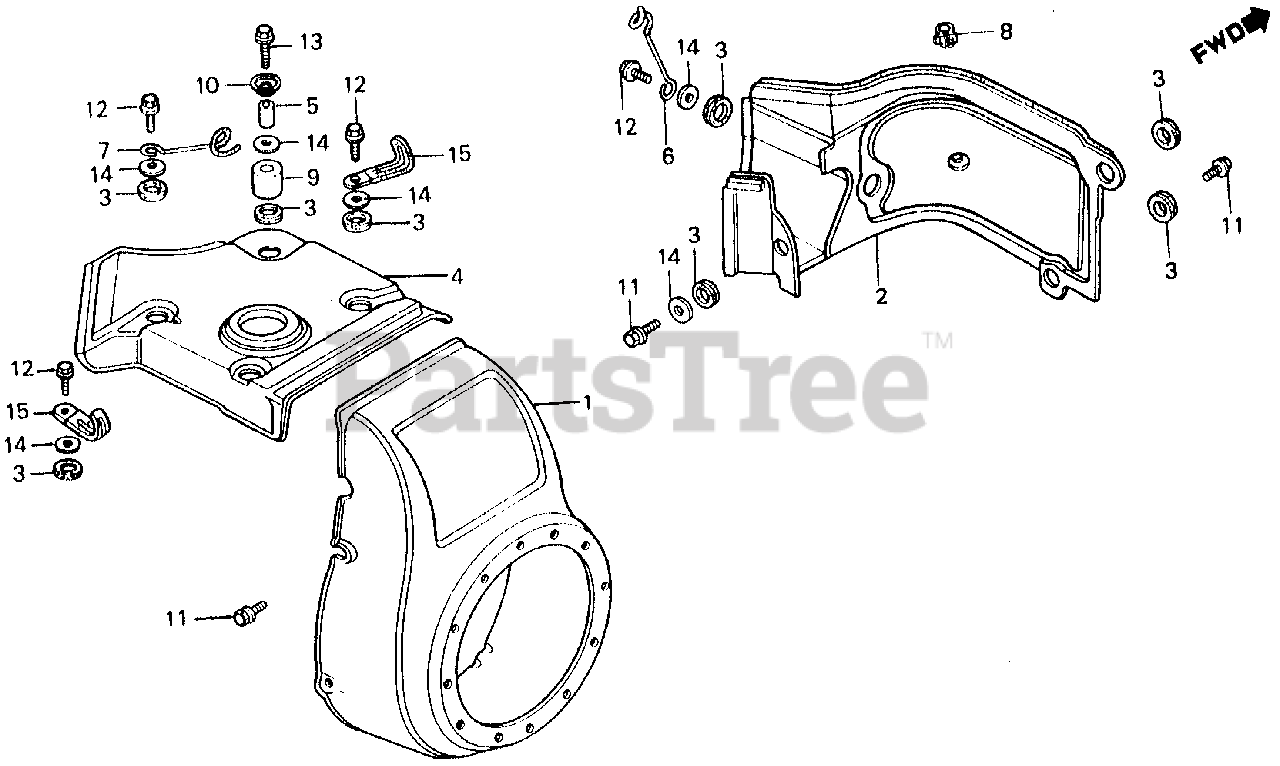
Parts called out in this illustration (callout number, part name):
1	COVER, FAN *R8* (BRIGHT RED) (NOT AVAILABLE)
2	SHROUD *R8* (BRIGHT RED)
3	RUBBER, MOUNTING
4	COVER, TOP *R8* (BRIGHT RED)
5	COLLAR, IGNITION COIL SETTING
6	CLAMP, IGNITION TUBE
7	CLAMP, IGNITION TUBE
8	CLIP, IGNITION WIRE (8MM)
9	RUBBER, STOPPER
10	PLATE, STOPPER
11	BOLT, FLANGE (6X12) (CT200)
12	BOLT, FLANGE (6X14)
13	BOLT, FLANGE (6X32)
14	WASHER, FLAT (20MM)
15	CLIP, WIRE HARNESS
